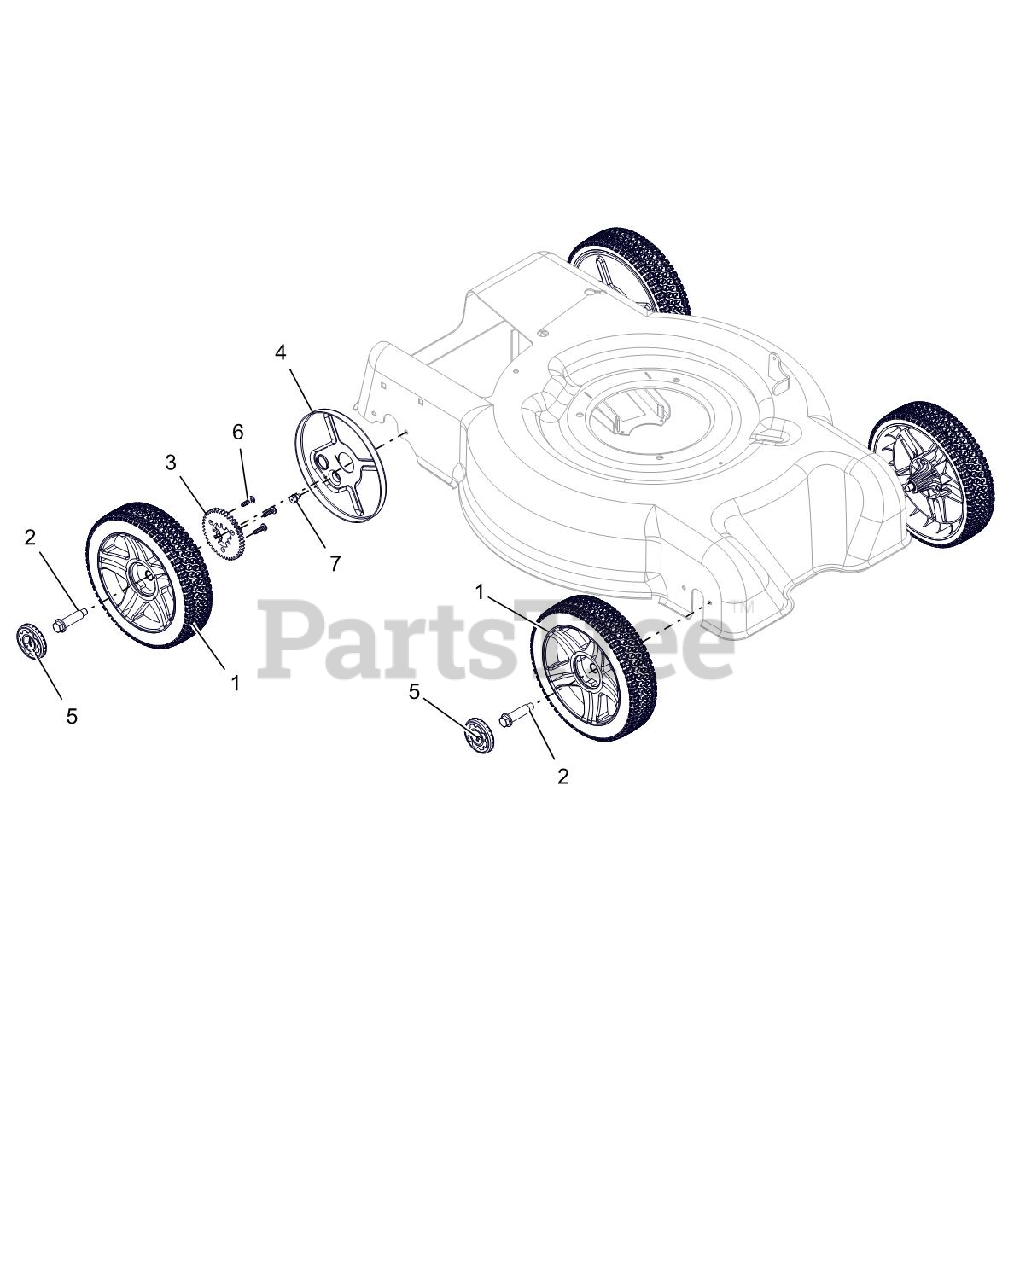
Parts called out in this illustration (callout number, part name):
1	ASSEMBLY, RAZOR WHEEL/BSHG
2	BOLT, WHEEL SHOULDER
3	GEAR, WHEEL
4	COVER, WHEEL
5	CAP, LM WHEEL HUB
6	SCR-TAP 12-14X.75PLSTITE @BLZC
7	@SCR-TAP .25-20X.37 HWH YWZ TR
